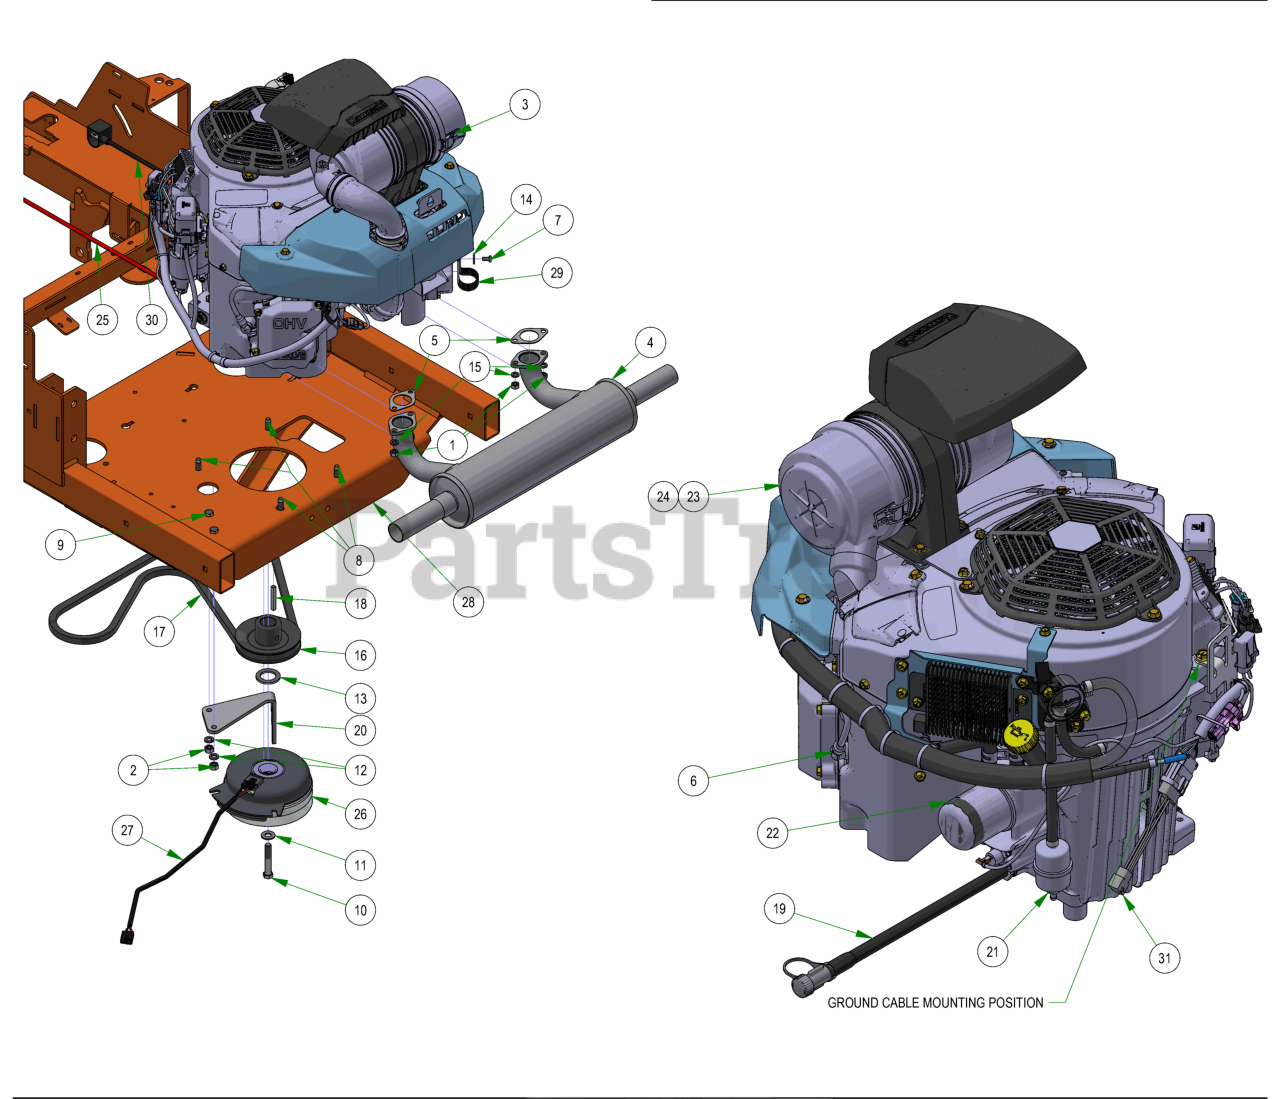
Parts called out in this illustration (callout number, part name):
1	M8-1.25 DIN 934 HEX NUT (CL.8) ZINC
2	3/8-16 HEX NUT ZINC
3	Kawasaki FX1000EFI 38.5HP
4	2019 Rebel/Rogue Kawasaki 1000 Muffler
5	Exhaust Gasket
6	Spark Plug - Kawasaki
7	M6-1.0 X 12MM DIN 933 HEX TAP BOLT (CL 8.8) ZINC
8	3/8-16 X 1-1/8HEX WASHER UNSLOT SERRATED (TRI-LOB) TRS ZINC
9	3/8-16 X 1-1/4 HEX CAP SCREW (GR.5) ZINC
10	7/16-20 X 2-1/2 HEX Bolt GR 8 W/ Patch
11	3/8 FLAT WASHER USS (1" OD) ZINC
12	3/8 SPLIT LOCKWASHER ZINC
13	1.140 ID X 1.750 OD X .132 THICK FLAT WASHER PLAIN
14	1/4 USS FLAT WASHER (3/4 OD) ZINC
15	5/16 SPLIT LOCKWASHER ZINC
16	4 3/4 Motor Pulley
17	2019 Rogue Pump Belt 68"
18	1/4 X 2 SQ MACHINERY KEY 1018 STL PLAIN
19	Kawasaki Oil Drain
20	PTO Engager Holder
21	Universal Inline Fuel Filter
22	Oil Filter
23	Canister Air Filter- Outer
24	Canister Air Filter- Inner
25	24" Red Battery Cable
27	Clutch Pigtail
28	2023 Rogue Frame - Painted
29	Diesel Hydraulic Hose Clamp
30	Starter Cable
31	Harness Adaptor for Kawasaki EFI Digital Display
